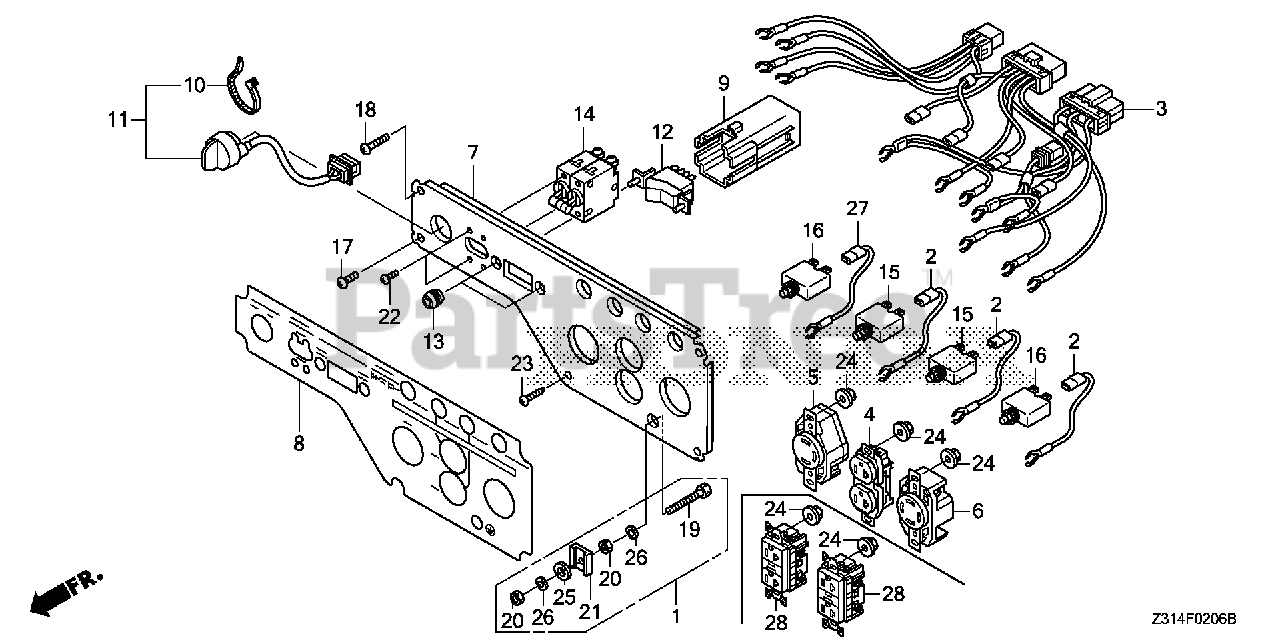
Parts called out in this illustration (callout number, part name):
1	TERMINAL SET, GROUND
2	SUB-WIRE ASSY.
3	WIRE HARNESS ASSY., CONTROL (CL-A1)
5	RECEPTACLE (30A-125V)
6	RECEPTACLE (30A-125/250V)
7	PANEL, CONTROL *NH105* (MAT BLACK)
8	MARK, PANEL (CL-A1)
9	CONNECTOR (12P)
10	BAND
11	SWITCH ASSY., ENGINE STOP
12	SWITCH ASSY., VOLT CHANGE
13	MOUNT, VOLT CHANGE SWITCH
14	BREAKER, CIRCUIT (21A)
15	PROTECTOR, CIRCUIT (20A)
16	PROTECTOR, CIRCUIT (30A)
17	SCREW, TRUSS (6X18)
18	SCREW, TRUSS (6X30)
19	BOLT, HEX. (6X28)
20	NUT, HEX. (6MM)
21	RETAINER (6MM)
22	SCREW, PAN (3X5)
23	SCREW, TAPPING (5X12) (PO)
24	NUT, FLANGE (4MM)
25	WASHER, PLAIN (6MM)
26	WASHER, SPRING (6MM)
27	SUB-WIRE ASSY. (A)
28	RECEPTACLE (20A-125V) (GFCI)
